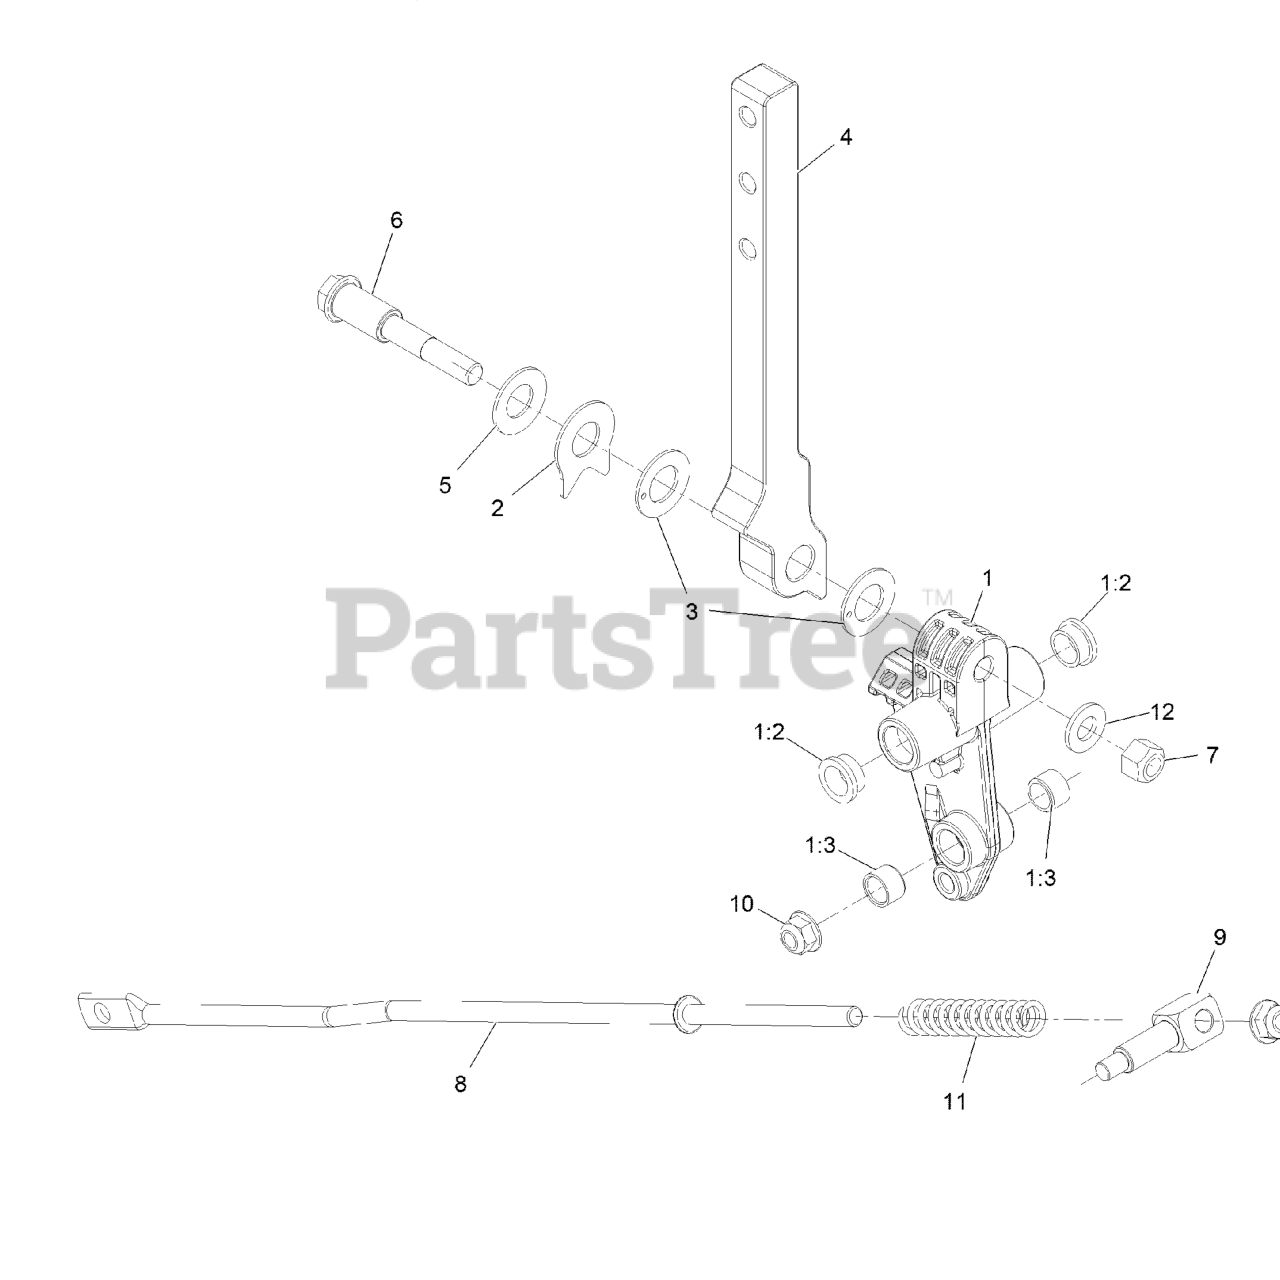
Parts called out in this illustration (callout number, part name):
1	CONTROL ARM ASM
1:2	BUSHING
1:3	BUSHING-SLEEVE
2	Spacer, Anti-Rotation
3	WASHER-FRICTION
4	Lever, Motion Control
5	WASHER-BELLEVILLE
6	Bolt-Pivot
7	NUT-LOCK, CONE
8	LINK-CONTROL
10	NUT-HF, NI
11	SPRING-RETURN, NEUTRAL
12	WASHER-FLAT
